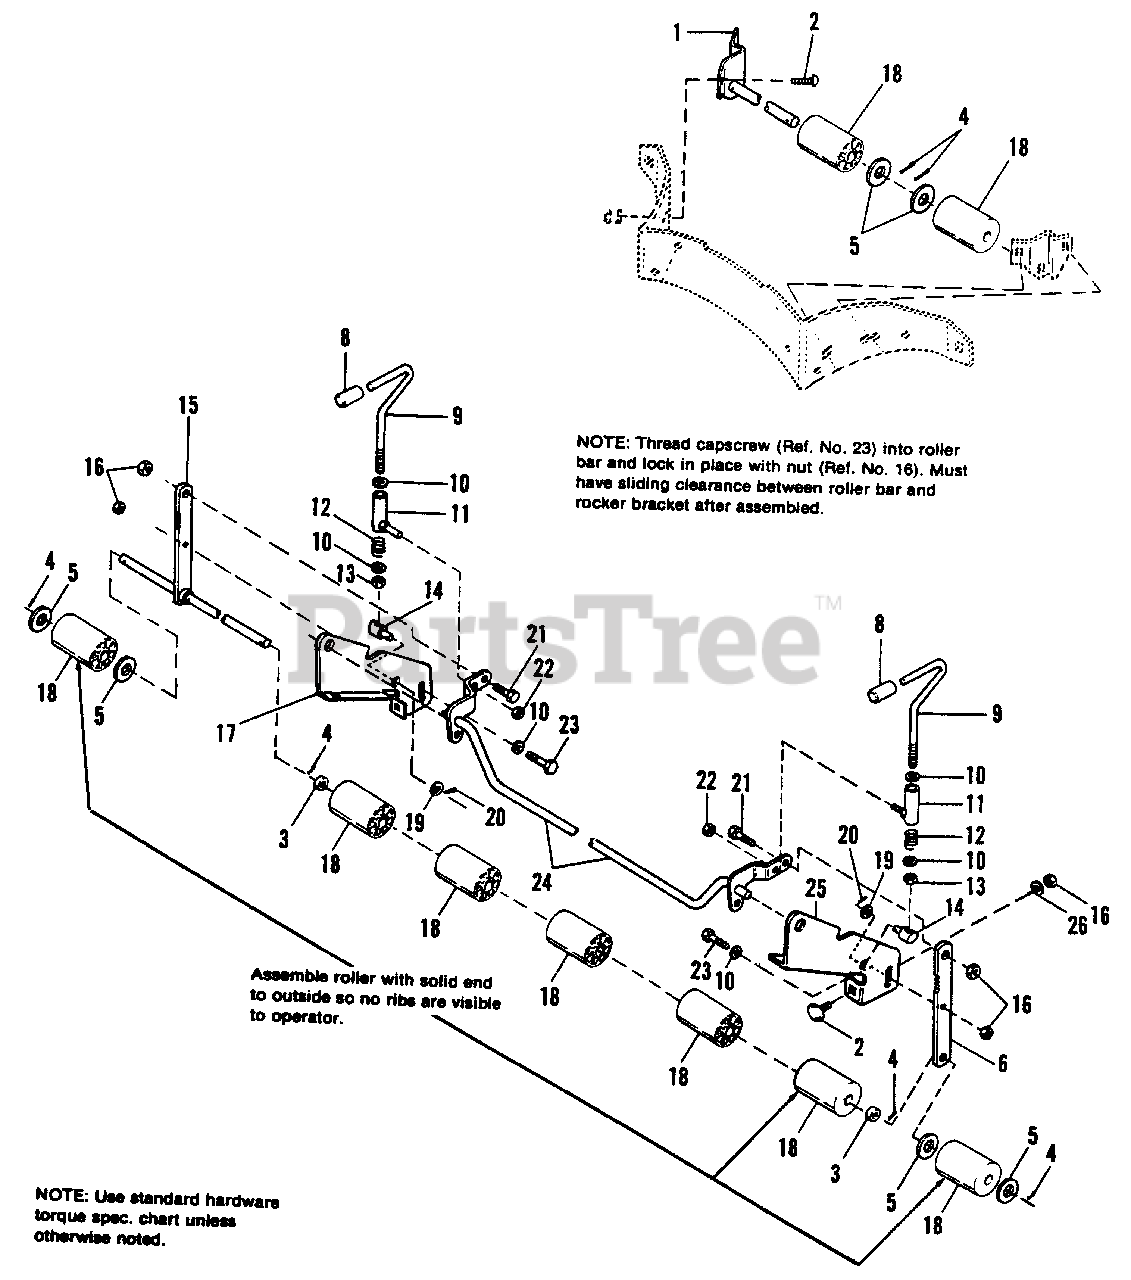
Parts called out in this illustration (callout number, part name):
1	BRACKET 8 SHAFT ASSY
2	BOLT, Carriage 3/8-16 x 3/4 (Qty 6 used on older models)
3	SPACER
4	PIN, Cotter 3/16 x 1
5	WASHER, Plain, 5/8
6	BAR, Roller
7	ROLLER
8	GRIP
9	HANDLE, Adjusting
10	WASHER, Plain, 3/8
11	SOCKET ASSY
13	NUT, Hex, Jam, 3/8-16
15	SHAFT ASSY, Roller
16	NUT, Hex, Full, 3/8-16
17	BRACKET, Roller, R H
18	ROLLER, 2-1/2 x 6-3/4
19	WASHER, Plain, 3/8
20	PIN, Cotter, 3/32 x 3/4
21	CAPSCREW, Hex Hd, 3/8-16 x 1
22	LOCKNUT, Hex, Full, 3/8-16
23	CAPSCREW, Hex Hd, 3/8-16 x 1, 5/8 Thd
24	ROCKER ARM ASSY
25	BRACKET, Roller, L H
26	LOCKWASHER, 3/8
